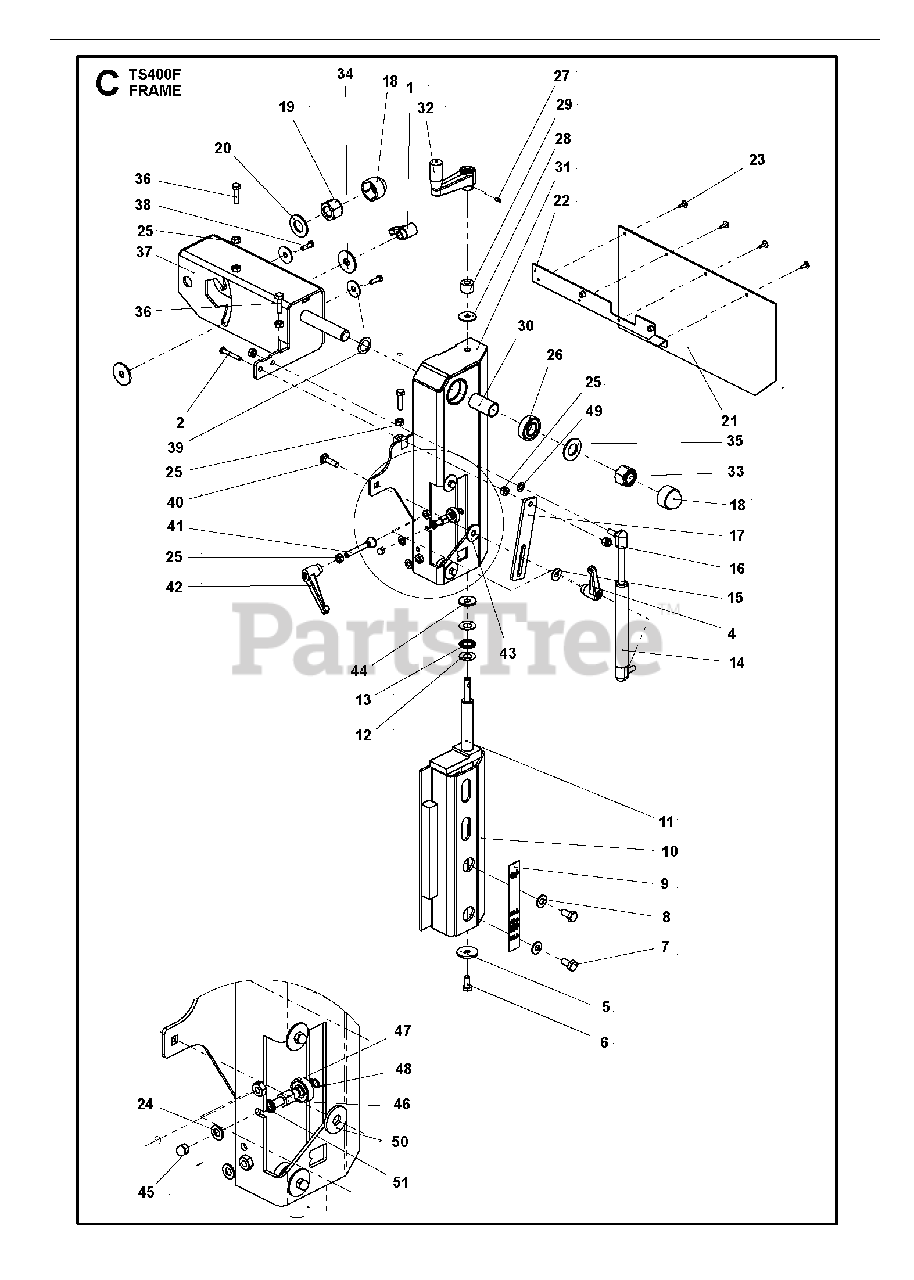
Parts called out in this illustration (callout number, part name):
8	WASHER
9	RULER, HEIGHT ADJUSTBLADES (TS
12	RONDELLE BUTEE AS 1528/
13	CAGE AIGUILLE AXK 1528 A/
15	RONDELLE ACIER L8 BICHRO/
16	HEXAGON LOCKING NUT
18	CHAPEAU GPN 1000/1077/
24	WASHER
25	HEXAGON NUT
28	SEPARATING LAYERS 3CARDBOARD 4
42	INDEXABLE HANDLE, NUT M8
43	ENTRETOISE 30/10.5/3/
47	BALL BEARING
49	WASHER
50	ENTRETOISE 30/10.5/3/
